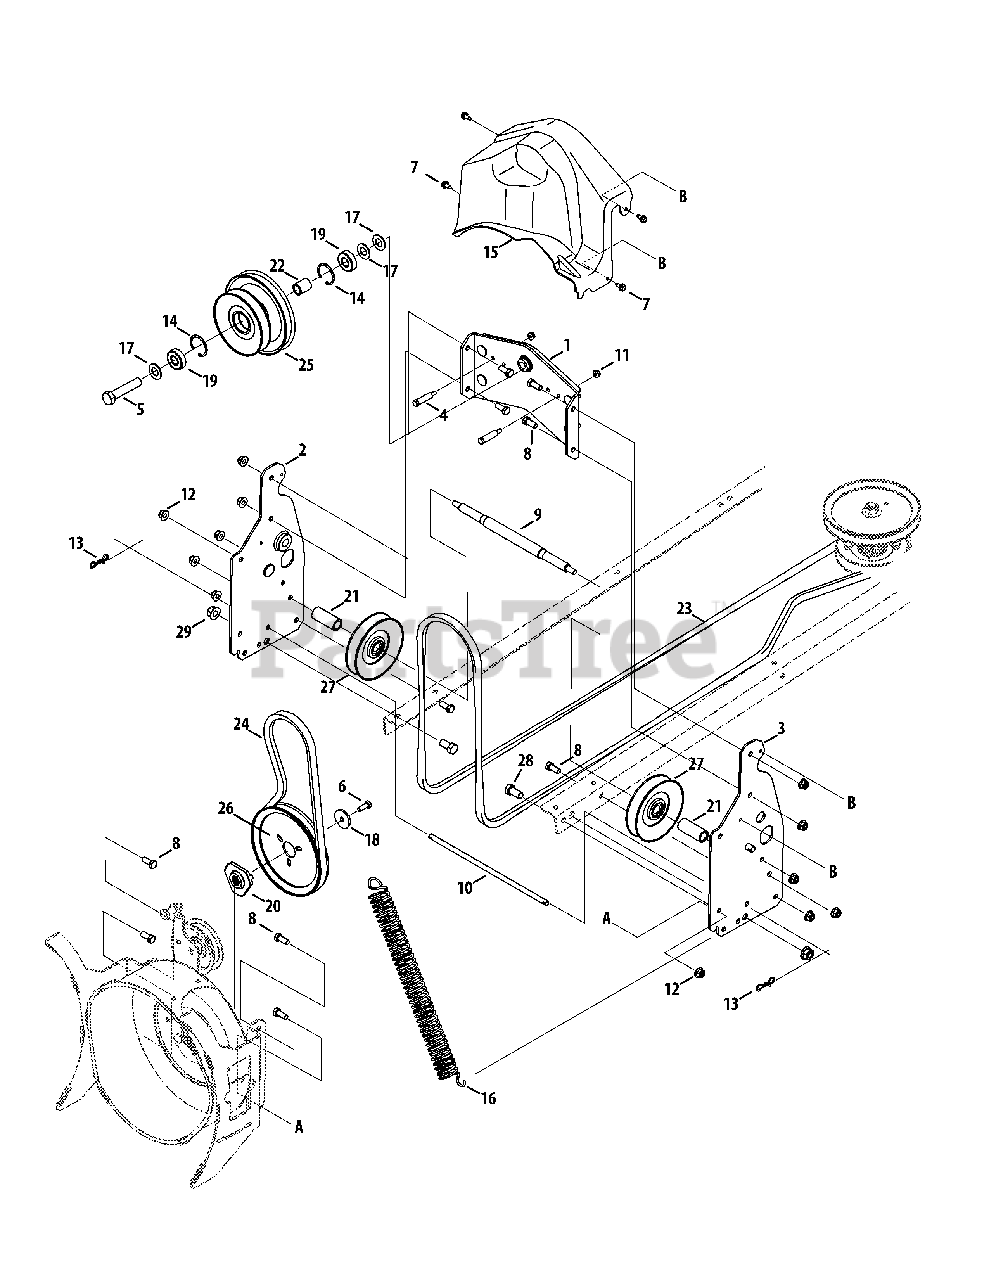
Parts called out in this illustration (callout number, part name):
1	Spindle Support Bracket
2	RH Frame Bracket
3	LH Frame Bracket
4	Shoulder Bolt
5	Hex Screw, 5/8-18 x 3.00
6	Hex Screw, 5/16-24 x .875
7	Hex Washer Screw, 1/4-20 x .625
8	Hex Screw, 3/8-16 x .880
9	Idler Support
10	Shaft, .375 x 12.3450
11	Flange Lock Nut, 1/4-20
12	Flange Lock Nut, 3/8-16
13	Pin, 7/16-1/2
14	Retainer Ring
15	Belt Cover
16	Extension Spring, 1.6 x 7.584
17	Flat Washer, .65 x 1.25 x .075
18	Flat Washer, .34 x 1.50 x .150
19	Ball Bearing, .625 x 40 x 12 x 6203
20	Adapter Pulley, .75
21	Spacer, .65 x .96 x 2.31
22	Spacer, .88 x .635 x 1.105
23	V- Belt, 138.4
24	V-Belt, 39.988
25	Double Pulley
26	Pulley, 7.25
27	Idler Pulley, 5.06
28	Hex Screw, 1/2-13 x 1.00
29	Flange Lock Nut, 1/2-13
